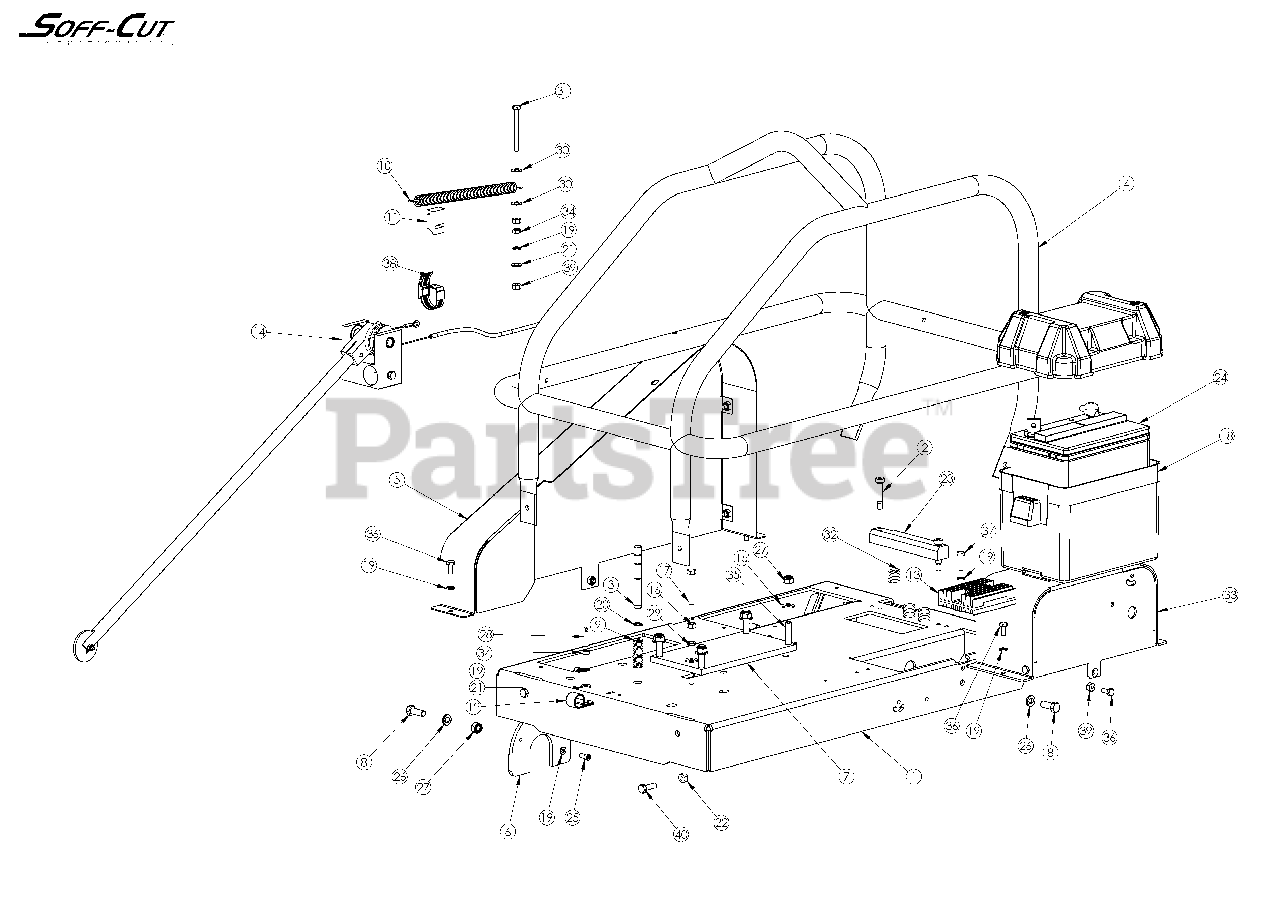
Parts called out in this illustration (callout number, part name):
15	FLAT WASH 3/8 STL CAD
17	5/16-18 X 2 HEX BOLT GRADE5
22	NYLOC NUT 5/16-18 CAD PL.
39	NYLOC NUT 1/4-20 CAD PL.
40	HEX BOLT 5/16-18-1 CAD GR 5
